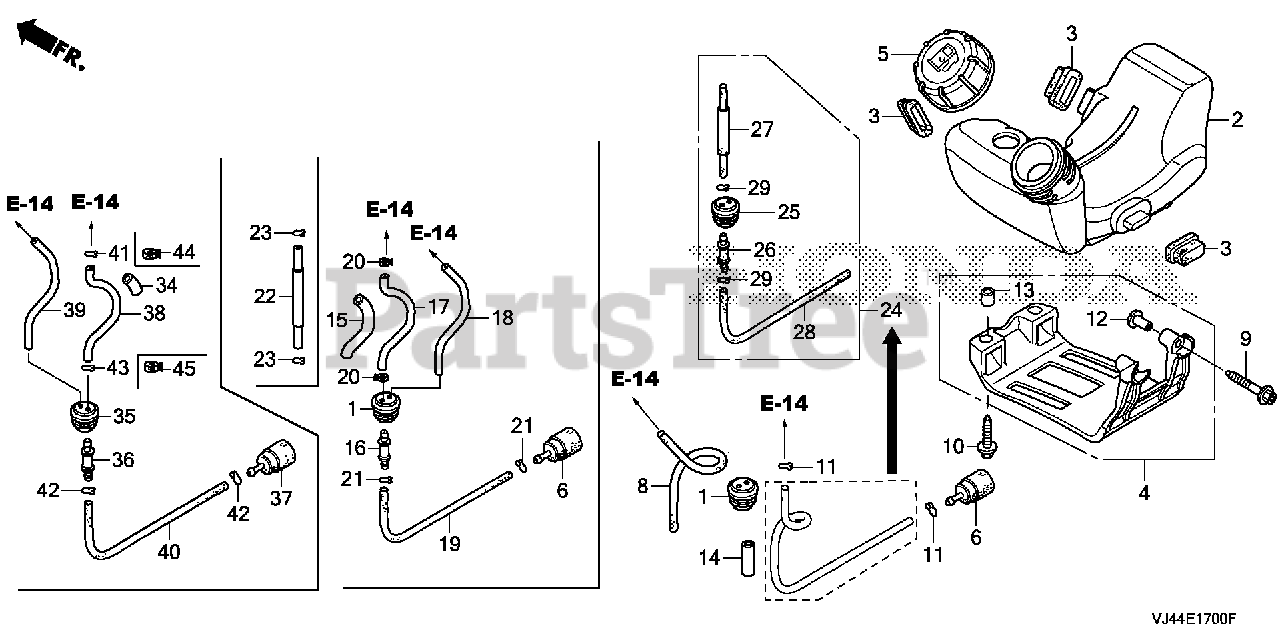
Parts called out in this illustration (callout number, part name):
1	GROMMET, FUEL TUBE
2	TANK, FUEL (FOR U.S.A.)
2	TANK, FUEL
3	RUBBER, TANK MOUNTING
4	GUARD, TANK
5	CAP ASSY., FUEL TANK
6	FILTER, FUEL
8	TUBE, FUEL RETURN
9	BOLT, SOCKET (5X30)
10	BOLT, SOCKET (5X16)
11	CLIP, TUBE
12	COLLAR, TANK GUARD
13	COLLAR A, HEAD COVER
14	PROTECTOR, TUBE
15	PROTECTOR, TUBE
16	JOINT, FUEL TANK
17	TUBE, FUEL
18	TUBE, FUEL RETURN
19	TUBE A, FUEL
20	CLAMP, TUBE
21	CLIP, TUBE
24	GROMMET ASSY., FUEL TANK
25	GROMMET, FUEL TUBE
26	FITTING
27	TUBE, FUEL FEED
28	TUBE A, FUEL
29	CLIP, TUBE
34	PROTECTOR, TUBE
35	GROMMET, FUEL TUBE
36	JOINT, FUEL TANK
37	FILTER, FUEL
38	TUBE, FUEL
39	TUBE, FUEL RETURN
40	TUBE A, FUEL
42	CLIP, TUBE (B1 5)
44	CLAMP, TUBE (D5.5)
45	CLAMP, TUBE (D5.5)
